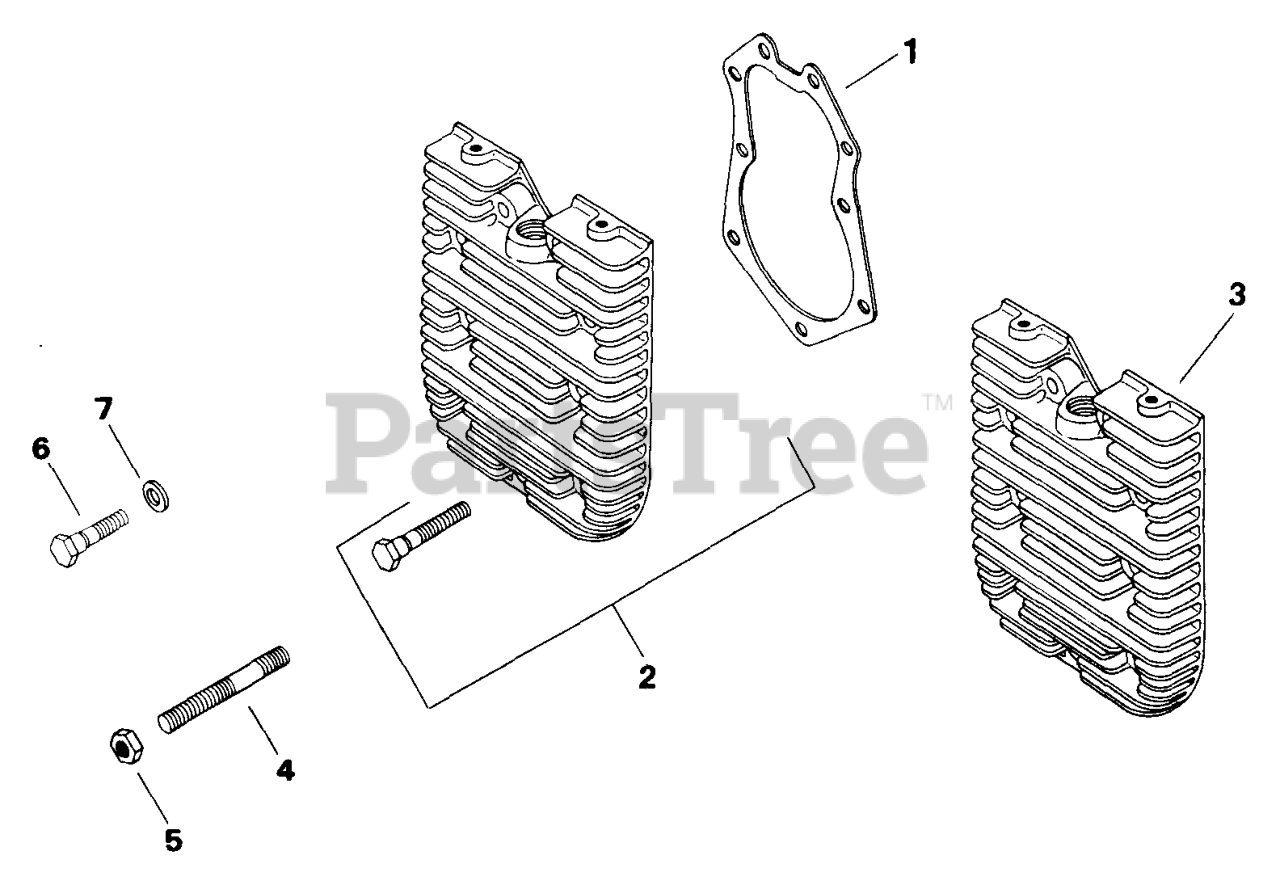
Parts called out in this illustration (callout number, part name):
2	KIT, CYLINDER HEAD - (#DSC)
3	KIT, CYLINDER HEAD - (#DSC)
5	NUT, 5/16-18 GRADE 5 USE 25 100 22-S
6	SCREW - DISCONTINUED
7	WASHER, FLAT 5/16"
